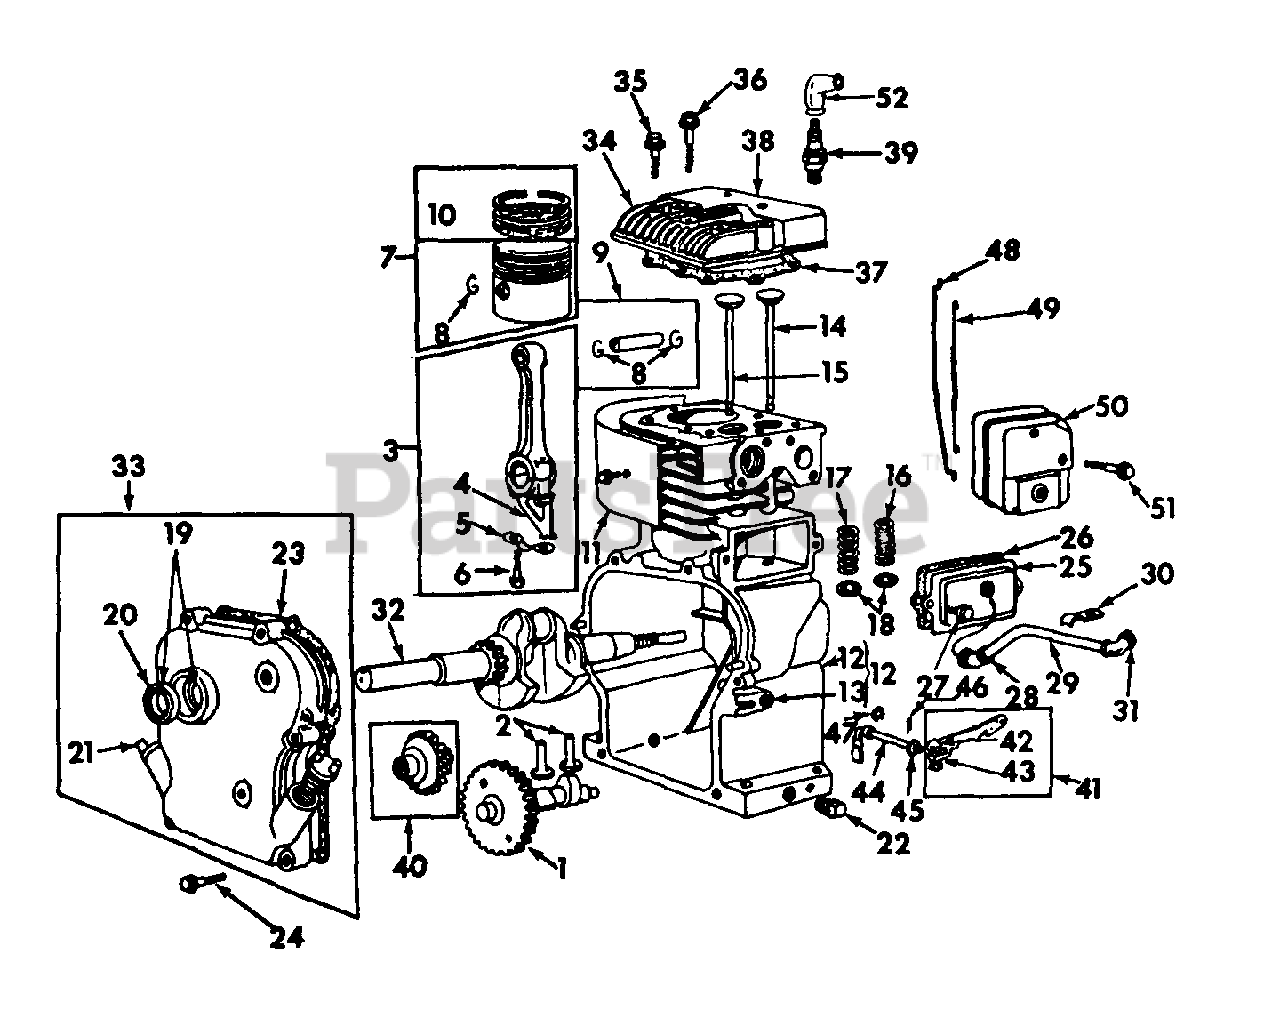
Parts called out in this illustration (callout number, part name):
2	TAPPET, VALVE
3	ROD ASSY, CONNECTING - STD
4	DIPPER, CONNECTING ROD
5	LOCK, SCREW HEAD
6	SCREW, CONNECTING ROD
7	PISTON ASSY, STD
8	RETAINER, PISTON PIN
9	PIN ASSY, PISTON - STD
10	RING SET, PISTON CHROME - STD
11	SHIELD CYLINDER
12	CYLINDER ASSY, ENGINE
13	BUSHING, GOVERNOR SHAFT
14	VALVE, INTAKE
15	VALVE, EXHAUST
16	SPRING, INTAKE VALVE
17	SPRING, EXHAUST VALVE
18	RETAINER, VALVE SPRING
19	BUSHING & OIL SEAL, COVER
20	OIL SEAL & SPACER, COVER
21	PLUG, OIL FILLER
22	PLUG, 1/4-18 AUTOMOTIVE SQ-HD OIL DRAIN
23	GASKET, CRANKCASE
24	SCREW, CRANKCASE COVER MTG
25	BREATHER, VALVE CHAMBER
26	GASKET, VALVE COVER
27	SCREW, BREATHER MTG
28	GROMMET, BREATHER
29	TUBE, BREATHER
30	CLAMP, BREATHER TUBE
31	GROMMET, BREATHER TUBE
33	COVER, CRANKCASE
34	HEAD, CYLINDER
35	SCREW, CYL HEAD-SHORT
36	SCREW, CYL HEAD-LONG
37	GASKET, CYLINDER HEAD
38	COVER, CYLINDER HEAD
39	PLUG, SPARK, CHAMPION
40	GEAR, GOVERNOR
41	LEVER ASSY, GOVERNOR
42	BOLT, GOVERNOR LEVER
43	WASHER, GOVERNOR LEVER
44	CRANK, GOVERNOR
45	WASHER, GOVERNOR CRANK
46	COTTER, GOVERNOR CRANK
47	RING, GOVERNOR CRANK RETAINER
48	LINK, GOVERNOR
49	SPRING, GOVERNOR LINK
50	MUFFLER, EXHAUST
51	SCREW, MUFFLER MOUNTING
52	ELBOW, SPARK PLUG INSULATOR
